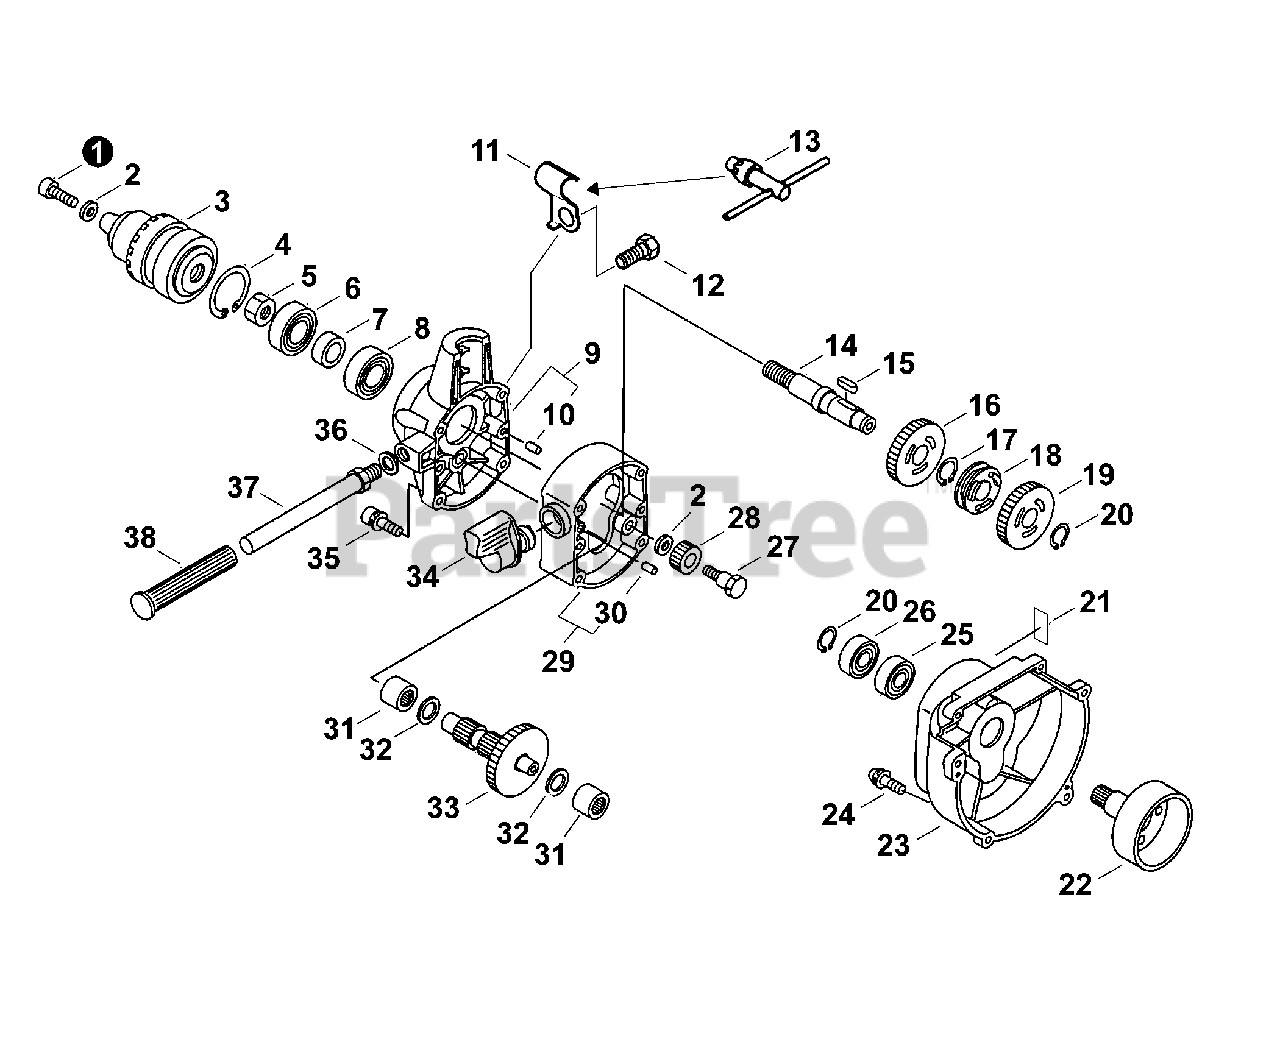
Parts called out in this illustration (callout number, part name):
1	SCREW - 6×20
2	WASHER - 6
4	RING, RETAINING - 32
5	NUT - 12
6	BEARING, BALL - 6002
8	BEARING, BALL - 6002
9	GEAR CASE ASY
10	PIN, DOWEL
11	SPRING, FLAT
12	BOLT - 10×15
13	KEY, CHUCK
14	SHAFT, AXLE
15	KEY, WOODRUFF - 4×16
16	GEAR, SPUR
17	RING, RETAINING - 15
18	NAIL, CLUTCH
19	GEAR, SPUR
20	RING, RETAINING - 12
21	LABEL - CAUTION -- HOT
22	DRUM, CLUTCH
23	CASE, FAN
24	SCREW - 4×16
25	BEARING, BALL - 6001
26	BEARING, BALL - 6001
27	BOLT, CLUTCH
28	GEAR, SPUR
29	CASE, GEAR
30	PIN, DOWEL
31	BEARING, NEEDLE
33	GEAR, SHAFT
34	LEVER, CLUTCH
35	SCREW - 5×55
36	WASHER - 10
37	HANDLE - FRONT
38	GRIP, HANDLE
